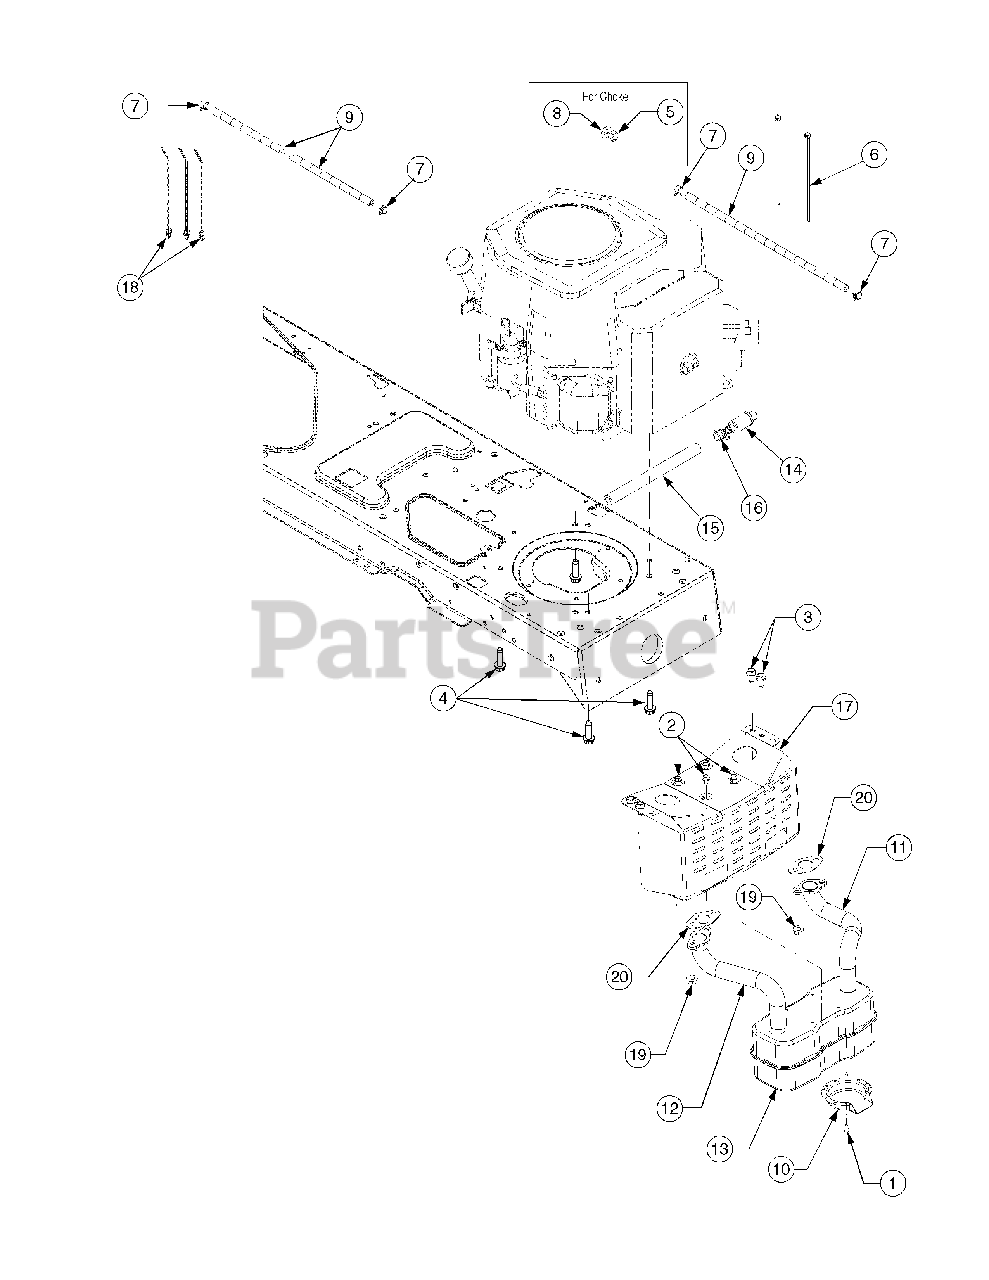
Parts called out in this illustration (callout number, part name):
1	Screw, #8-18, 0.500
2	Screw, Self-tapping, 1/4-20, 0.500
3	Screw, Hx. Wash. Hd. Tapp 5/16-12 x .75
4	Screw, Hx. Wash. Hd. Tapp 3/8-16 x
5	Nut, Hex Flange Lock, 3/8-16, Gr5
6	Cable, Tie, 3/16 x .05 x 7.4
7	Clamp, Hose, .490 Dia.
8	Washer, Flat, .406 x .875 x .059
9	Hose, Fuel Line, 45 in
10	Deflector, Muffler
11	Pipe, Exhaust, LH
12	Pipe, Exhaust, RH
13	Muffler, Dual Inlet
14	Drain, Oil
15	Hose, Extension, Oil Drain, 12in
16	Cap, Oil, Drain
18	Tie, Cable, Push Mount 7.5 Lg
19	Nut, M8, 1.25
20	Gasket, Exhaust
